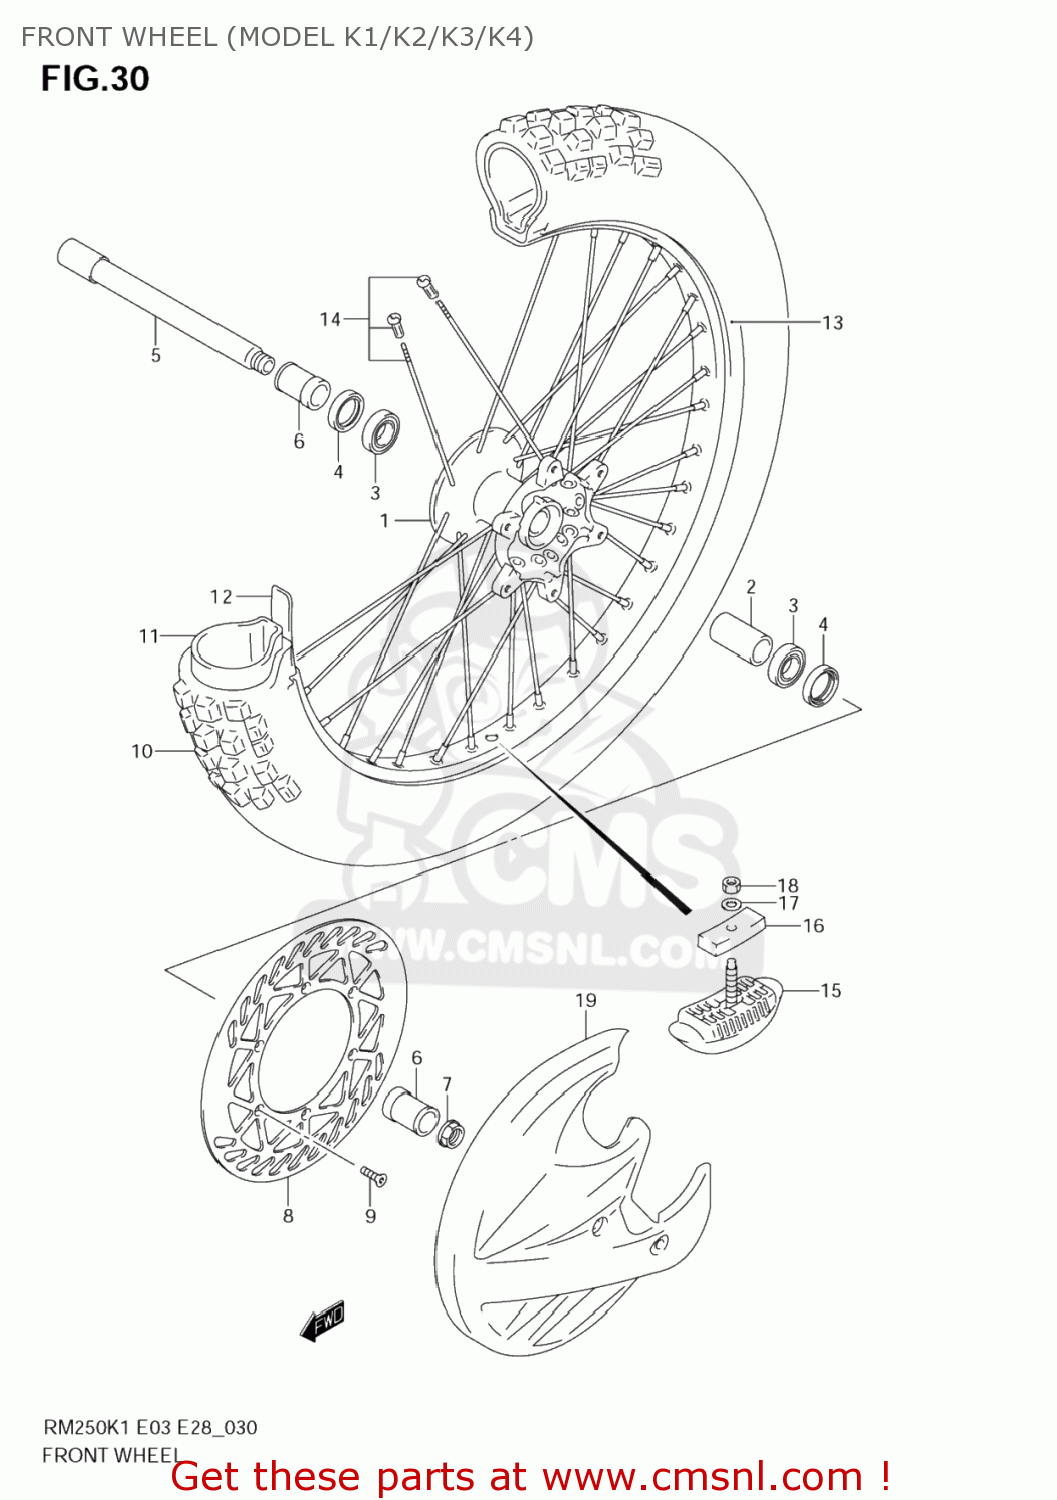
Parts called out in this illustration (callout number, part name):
1	HUB,FR WHEEL
2	SPACER,FR HUB BEARING
3	BEARING
4	SEAL,OIL(28X37X7)
5	AXLE,FR
6	SPACER,FRONT A
7	NUT
8	DISC,FR BRAKE
9	SCREW
10	TIRE,FR(80/100 21)
11	TUBE
12	PROTECTOR,WHEEL INNER
13	RIM,FR WHEEL(1.85X20)
14	SPOKE SET,FR WHEEL
15	STOPPER,BEAD
16	CUSHION,BEAD STOPPER
17	WASHER
18	NUT
19	COVER,FRONT DI
